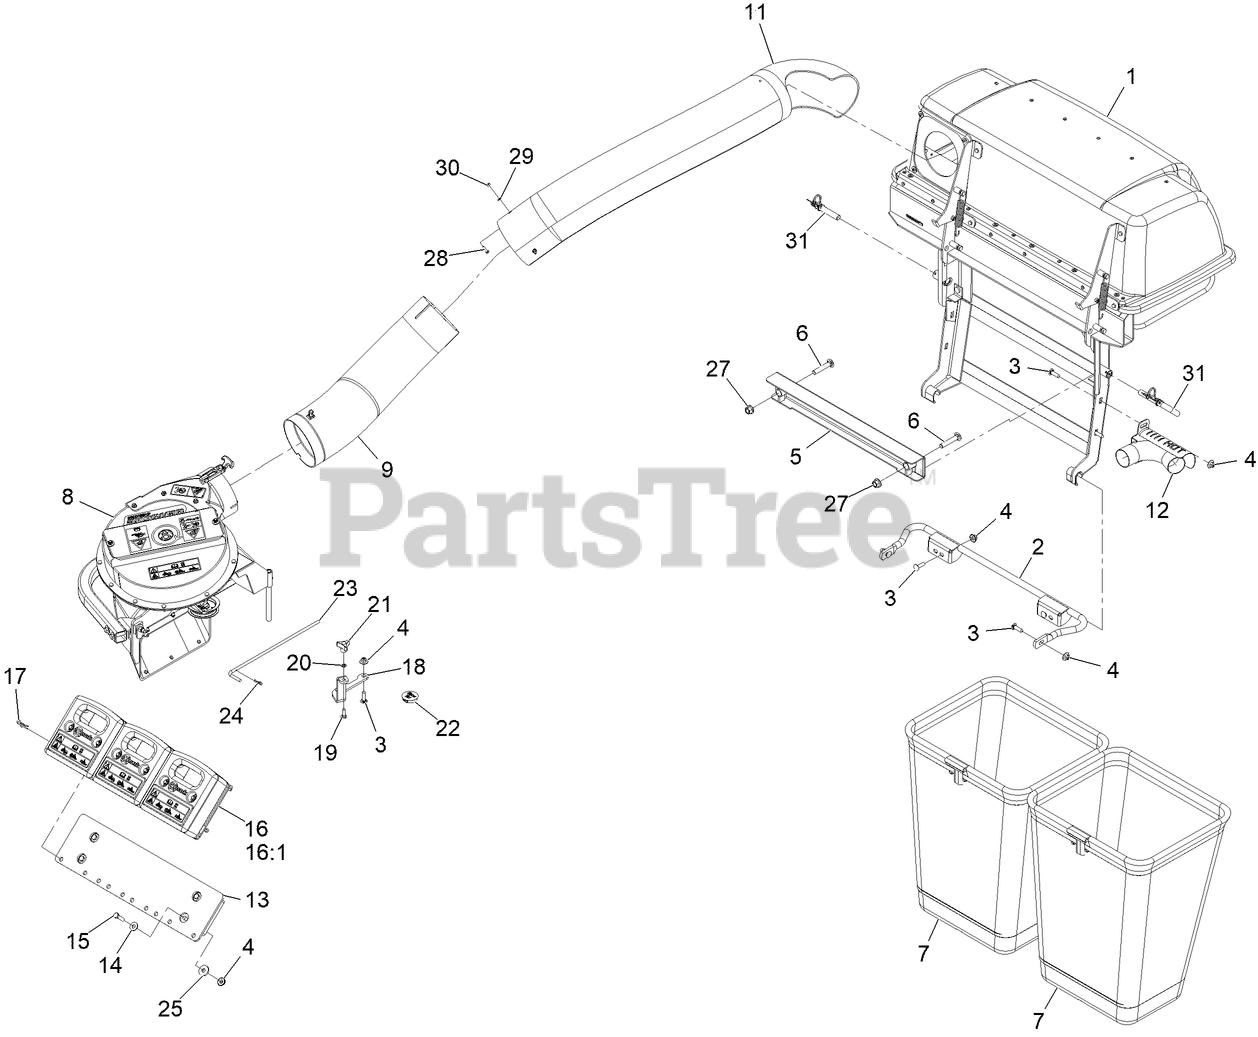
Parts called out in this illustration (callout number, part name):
2	MOUNT-BAGGER, LOWER
3	Bolt-Carriage 3/8-16 X 1 1/4
4	Nut-Nyloc 3/8-16 Flg
5	MOUNT-BAGGER, UPPER
6	SCREW-CARR
7	BAG AND FRAME ASM
8	ASM, BLOWER SMALL - SVC ONLY
9	LOWER TUBE ASM
11	TUBE-UPPER
12	EXHAUST DIVERTER ASM
13	WLD, MOUNT TOEBOARD WEIGHT
14	WASHER-FLAT
15	SCREW-HH
16	ASM,CAST WEIGHT
16:1	DECAL-WARNING WEIGHT
17	PIN-HAIR
18	BRACKET, SMALL UV BELT COVER
19	BOLT-CARR
20	RING-RETAINING, BOLT
21	KNOB-3 PRONG
22	PLUG, BLACK NYLON 1.75
23	PIN,CHUTE PIVOT
24	PIN-COTTER
27	Nut-Lock 1/2-13
28	SCREW-HWH
29	WASHER-FLAT
30	NUT-LOCK, NI
31	PIN-MOUNT, BAGGER
